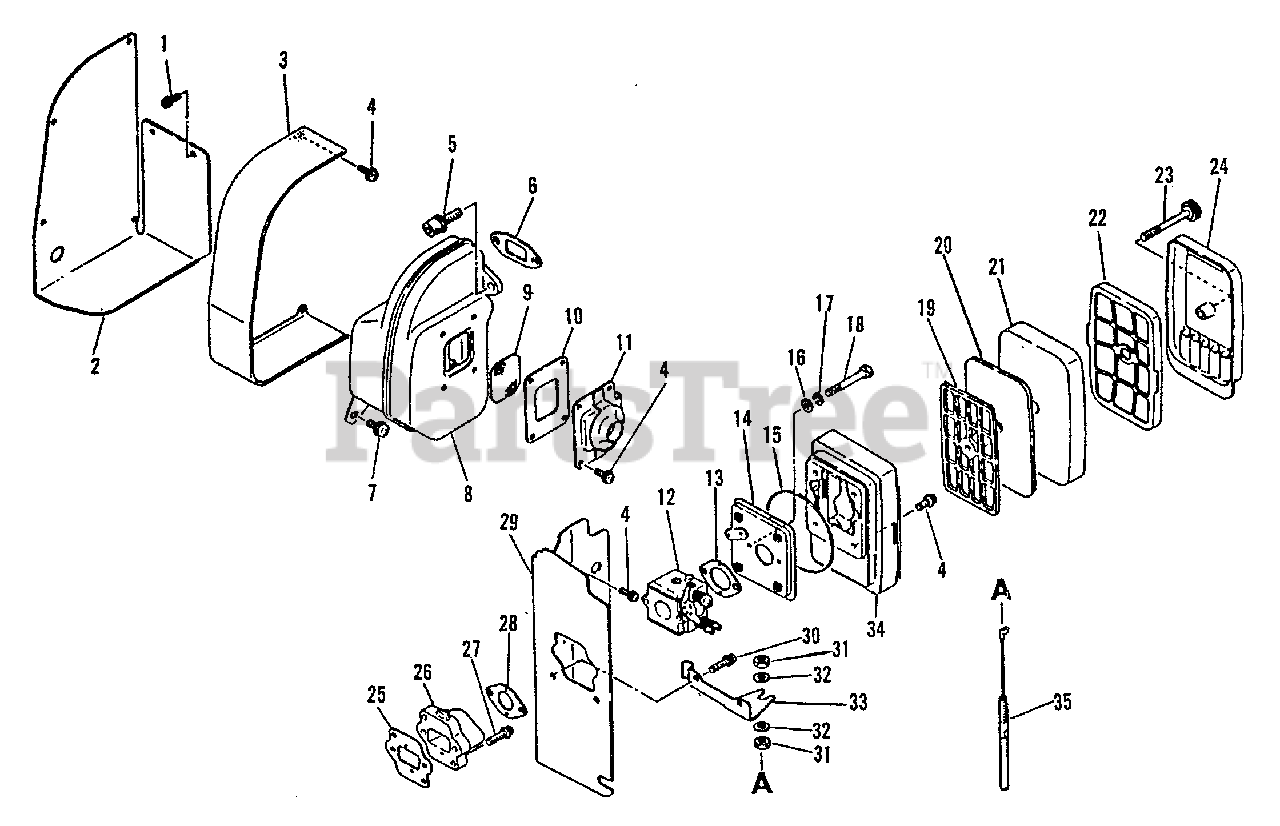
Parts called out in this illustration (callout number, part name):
1	SCREW 4×14
2	INSULATOR
3	COVER, MUFFLER
4	SCREW 4×10
5	SCREW - 6×20
6	GASKET, MUFFLER
7	SCREW 5×10
8	MUFFLER
9	SCREEN, SPARK ARRESTER
10	GASKET, MUFFLER
11	GUIDE, EXHAUST
12	CARBURETOR
13	GASKET, INTAKE
14	BRACKET
15	GASKET
16	WASHER, FLAT 5.5×10×0.8
17	WASHER, SPRING 5
18	BOLT
19	RETAINER, AIR FILTER
20	FILTER, AIR
21	FILTER, AIR
22	HOLDER, AIR FILTER
23	THUMBSCREW
24	COVER, AIR FILTER
25	GASKET, CARBURETOR
26	INSULATOR, INTAKE
27	SCREW 5×25
28	GASKET, INTAKE
30	SCREW 5×20
33	CLIP
34	CASE, AIR FILTER
35	CABLE, THROTTLE
